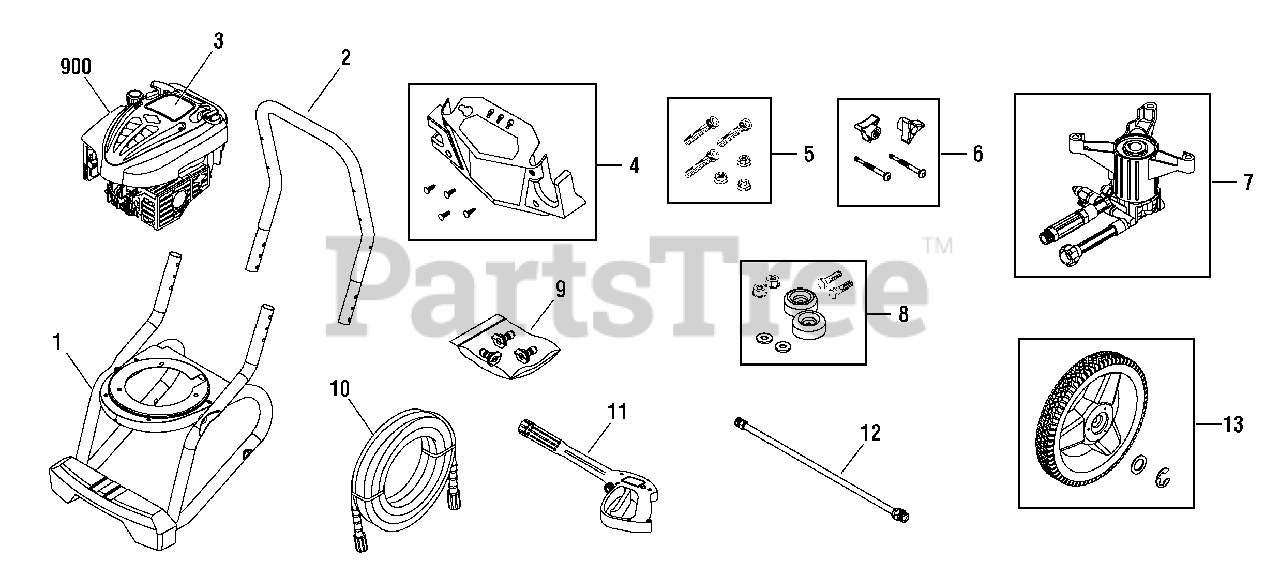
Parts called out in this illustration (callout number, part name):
5	KIT, Hardware, Pump Mounting
6	KIT, Hardware, Handle
7	PUMP
8	MOUNT, Vibration
9	KIT, QC Nozzles
10	HOSE
11	GUN
12	EXTENSION, QC
900	** ENGINE
